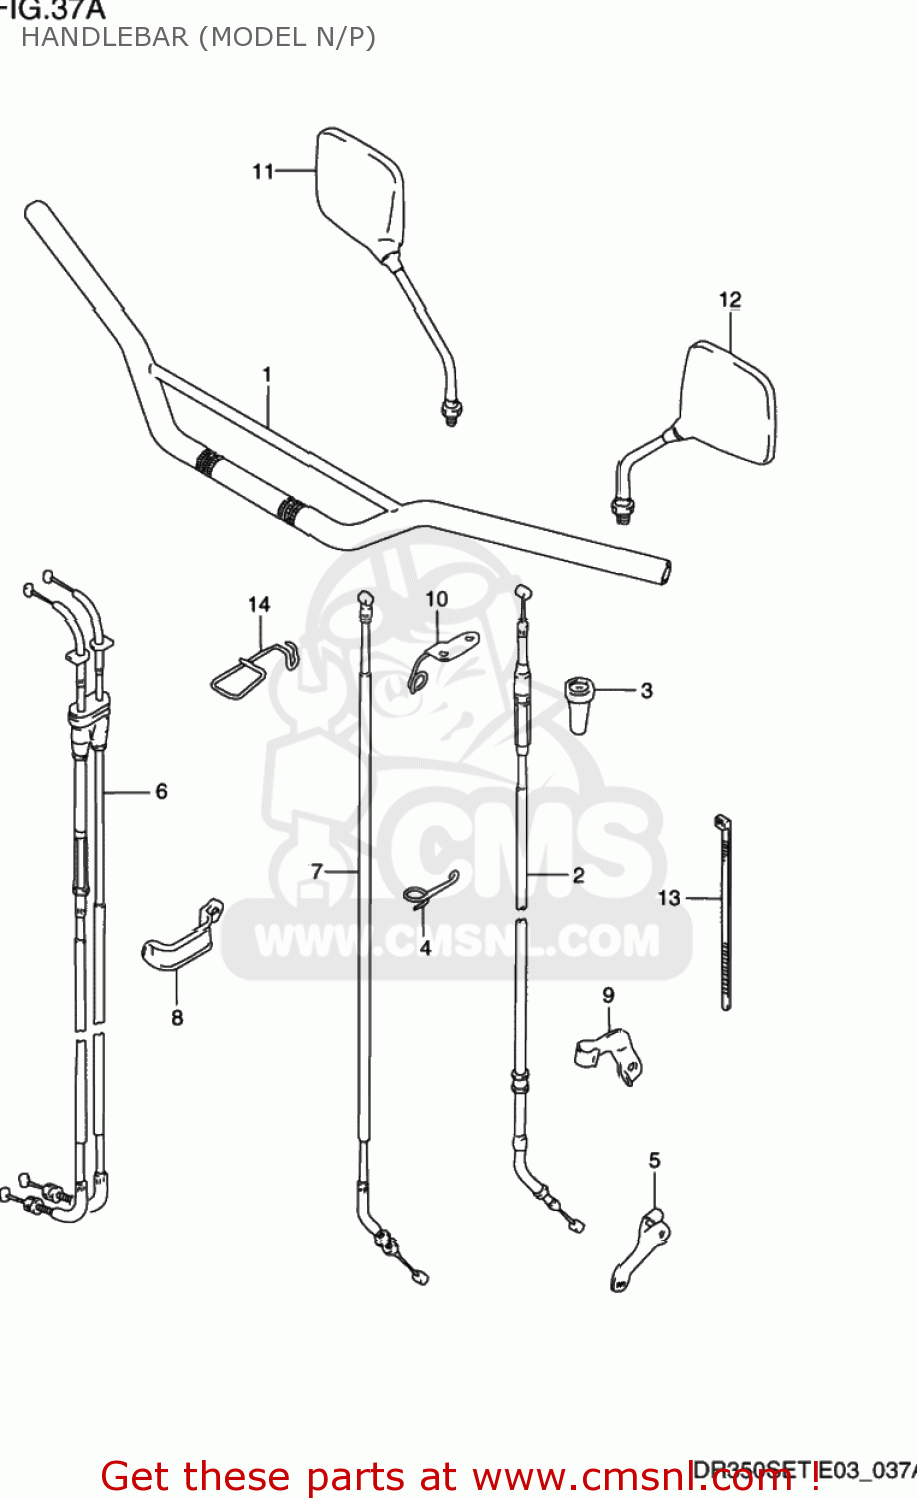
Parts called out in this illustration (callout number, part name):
1	HANDLEBAR
2	CABLE ASSEMBLY,CLUTCH
3	BOOT,CLUTCH CABLE
4	GUIDE,CLUTCH CABLE
5	STOPPER,CLUTCH CABLE
6	CABLE ASSY,THROTTLE
7	CABLE ASSY DECOMP
8	CLAMP
9	CLAMP,CLUTCH CABLE
10	GUIDE,CABLE
11	MIRROR ASSEMBLY,REAR VIEW
12	MIRROR ASSEMBLY,LEFT
13	CLAMP(L:100)
14	GUIDE,THROTTLE CABLE
